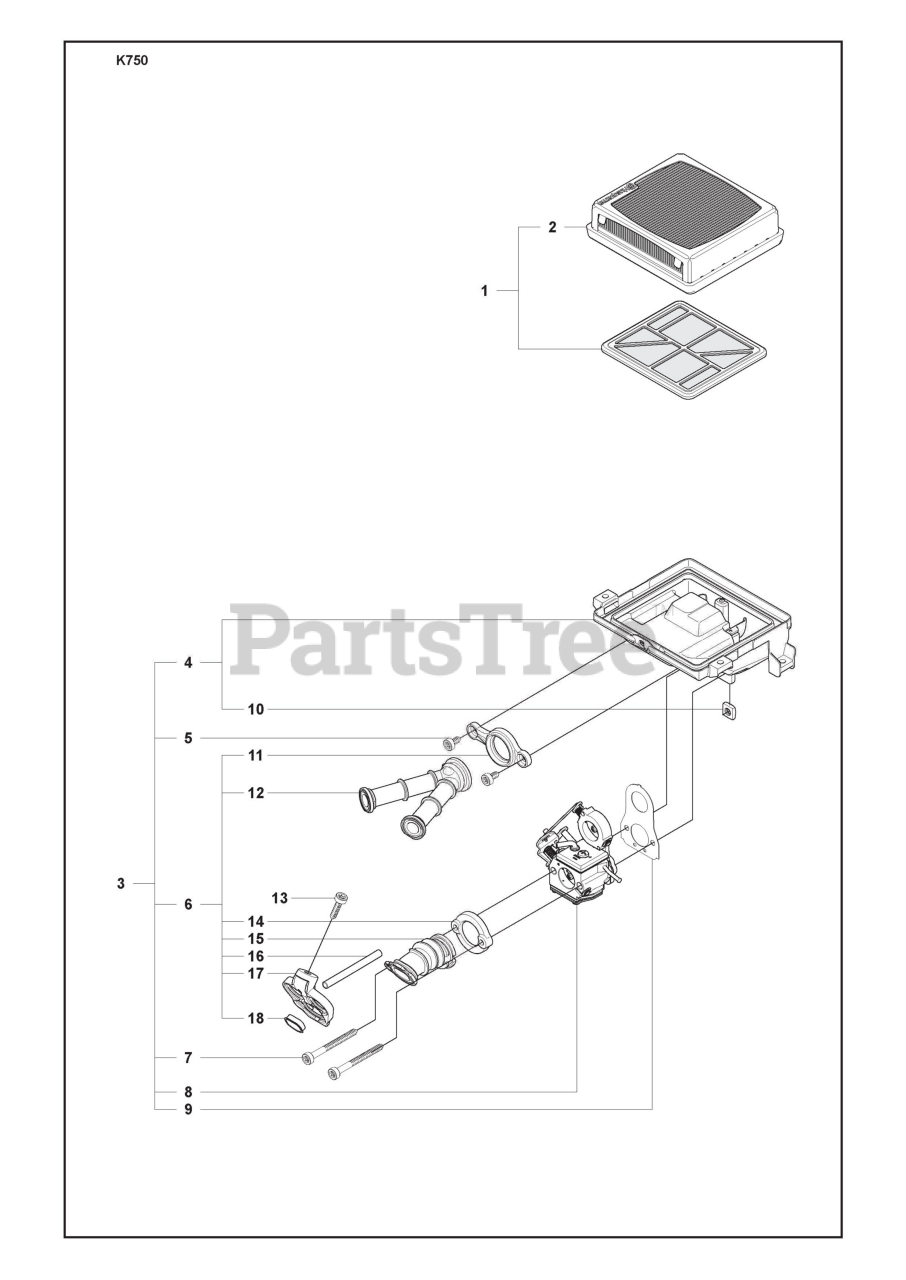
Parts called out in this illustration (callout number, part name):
1	FILTER
2	AIR FILTER PAPER
3	CARBURETTOR BRACKET
4	CARBURETTOR BRACKET
6	INLET PIPE
8	CARBURETTOR
9	GASKET CARBURETTOR
11	FLANGE INLET PIPE
12	INLET PIPE
14	FLANGE INLET PIPE
15	INLET PIPE
16	IMPULSE HOSE
17	PLATE
18	INSERT
